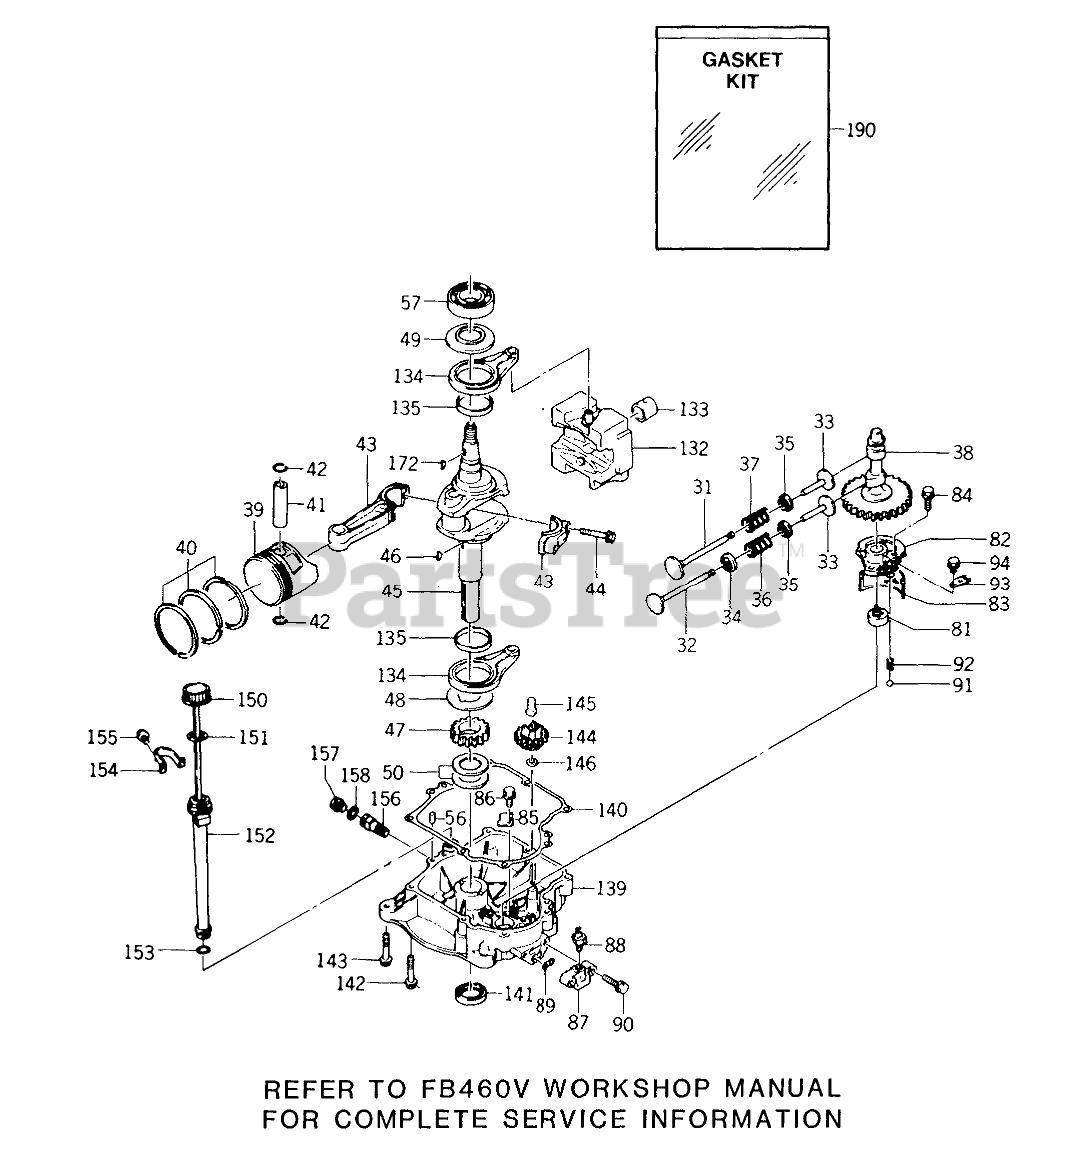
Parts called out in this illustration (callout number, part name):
31	Intake Valve
32	Exhaust Valve
35	Retainer-Spring
36	Spring-Valve
37	Spring-Valve
38	Cam Shaft
40	Piston Ring Set
41	Pin-Piston
42	Ring-Snap
43	Connecting Rod Ass-y-Standard (includes item 44)
45	Crankshaft Complete
46	Key-Woodruff
47	Gear
50	Shim (1.18)
56	Dowel Pin
57	Ball Bearing
81	Oil Pump Assy
82	Cover-Pump
83	Filter-Oil
84	Bolt-Flanged (8X25)
86	Bolt 5 x 8
88	Oil Pressure Switch
90	Bolt 8x30
93	Plate
94	BOLT-FLANGED (6X10)
132	Weight Complete (includes item 133)
133	Bushing
134	Rod Assy (includes item 135)
135	Bearing Plane
140	Gasket
142	Bolt-Flanged (8X45)
143	Bolt-Flanged (8X25)
144	Governor ASM
145	Sleeve
151	Gasket
153	O-RING (16mm)
155	Bolt
157	Plug
158	Gasket
172	Key-Woodruff
190	Overhaul Gasket Set
